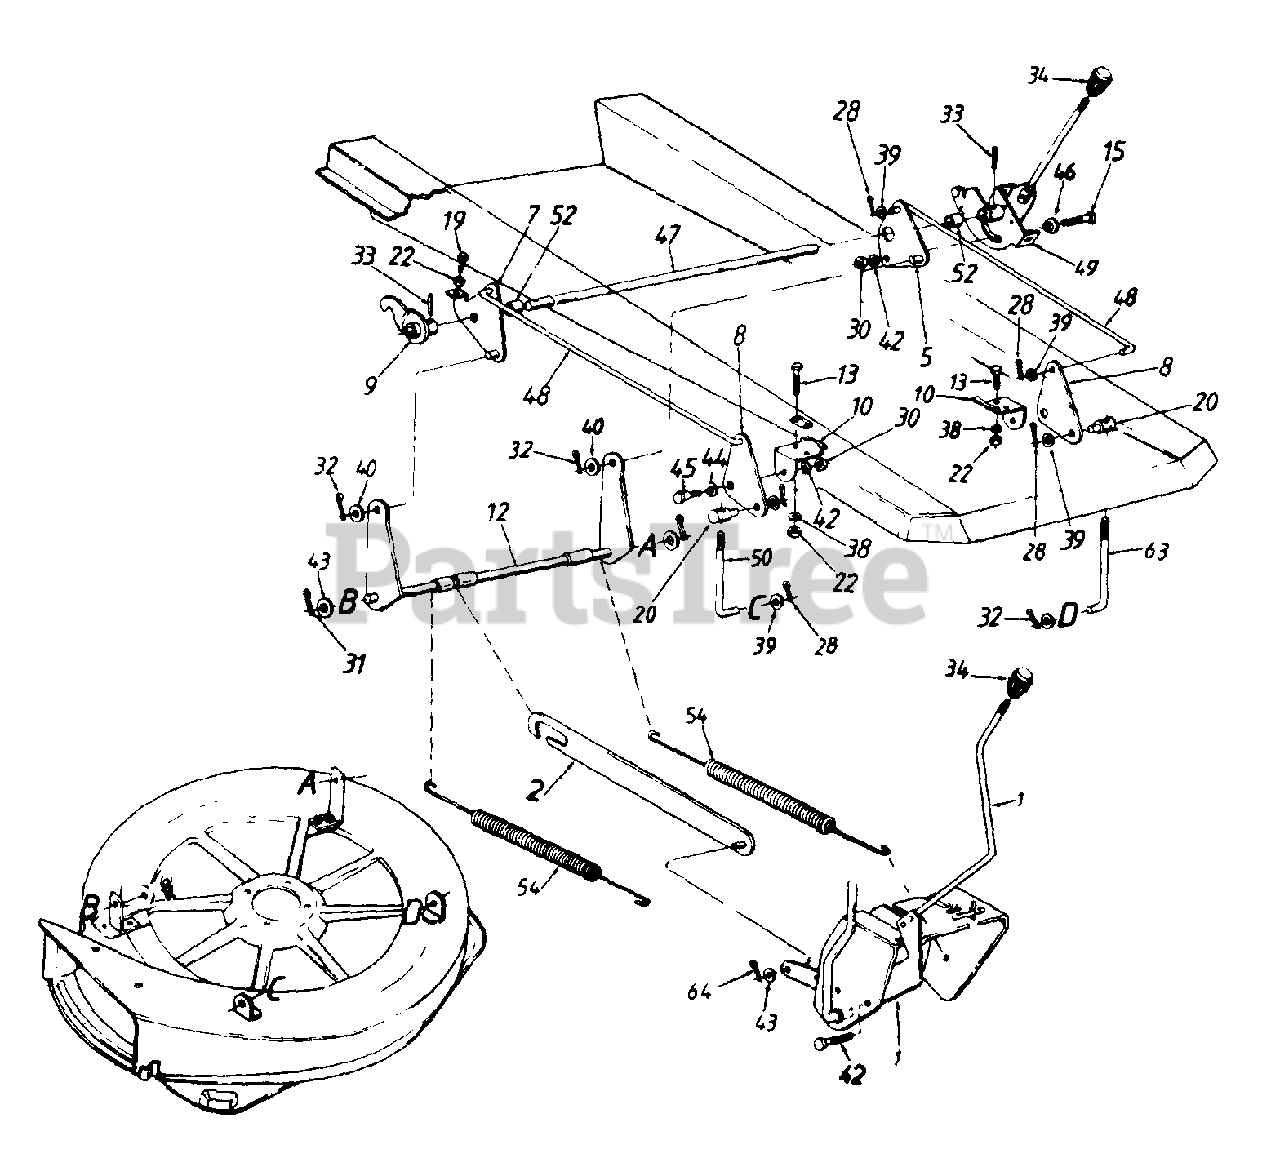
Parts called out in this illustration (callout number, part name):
7	Deck Lift Brkt. Ass'y.
8	Deck Lift Bracket
9	Deck Lift Float Brkt Ass'y.
10	Deck Lift Pivot Brkt.
15	Hex Bolt 3/8-16 x 1" Lg.
19	Hex Wash.-Tap Scr. 5/16-18 x 1.25" Lg.
20	Ferrule
22	Hex Nut 5/16-18 Thd.
28	Cotter Pin 3/32" Dia.
30	Hex Nut 3/8-16 Thd.
31	Internal Cot. Pin 1/2" Dia.
32	Int. Cot. Pins 3/8" Dia.
33	Spring Pin Spir. 1/4" Dia.
34	Knob
38	L-Wash 5/16" I.D.
39	Fl-Wash. .385 I.D. x .62
40	Fl-Wash. .635 I.D. x 1.12
42	L-Wash. 3/8" I.D.
43	Fl-Wash. .385 I.D. x .87 O.D.
44	Spring Washer .530 I.D.
45	Shld. Bolt .500" Dia. x .215"
46	Shld. Spacer .625" I.D.
47	Rear Hgt. Adj. Shaft
50	J-Bolt 3/8-24 x 5.25" Lg.
52	Spacer .885 I.D.
54	Ext. Spring 13.25" Lg.
63	J-Bolt 3/8-24 x 5.4" Lg.
64	Cotter Pin 1/8" Dia.
